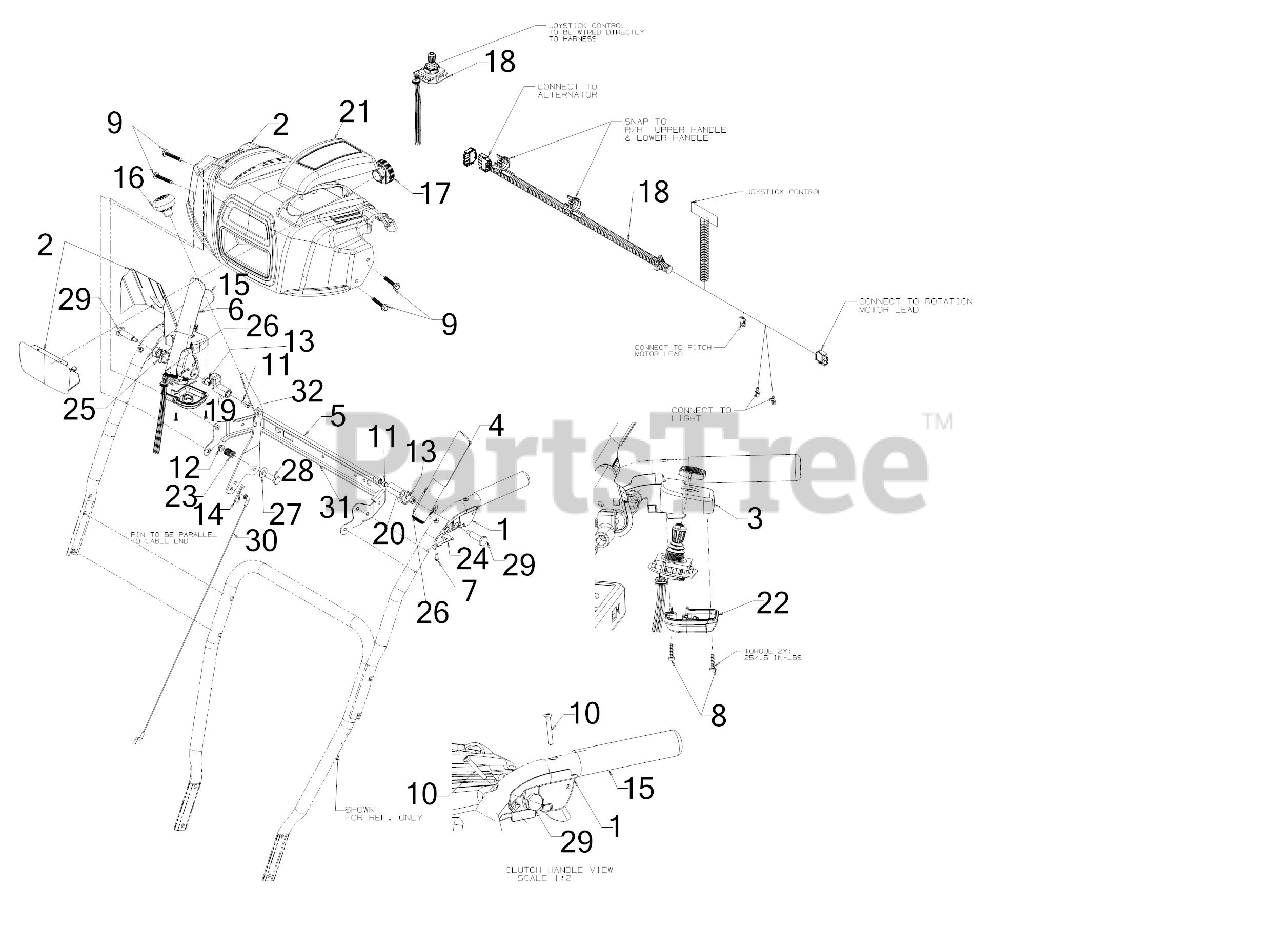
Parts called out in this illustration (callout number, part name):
1	CLUTCH LOCK HANDLE ASSEMBLY (LH)
2	HANDLE PANEL ASSEMBLY
3	CLUTCH LOCK HANDLE ASSEMBLY (RH)
4	HANDLE ASSEMBLY (LH)
5	PIVOT ROD
6	ENGAGEMENT HANDLE ASSEMBLY (RH) (RED)
7	SCREW #8-16 x .50
8	SCREW .159 x .610
9	SCREW 1/4-20 x 1.625
10	SCREW #10-24 x 1.375
11	SCREW 1/4-20 x .50
12	FLANGE LOCK NUT
13	HEX NUT W/PATCH
14	INTERNAL COTTER PIN
16	SHIFT KNOB
17	HEADLIGHT ASSEMBLY
18	4-WAY ELEC CHUTE HARNESS
19	LOCK PLATE
20	CLUTCH LOCK CAM
21	HANDLE COVER PANEL
22	JOYSTICK HOUSING COVER
23	COMPRESSION SPRING
24	CLUTCH SPRING
25	TORSION SPRING
26	RUBBER BUMPER
27	FLAT WASHER
28	SHOULDER SCREW
29	SHOULDER SCREW .437 x 1.345 1/4-20
30	SPEED SELECTOR CABLE (PLASTIC)
32	SHIFT LEVER
